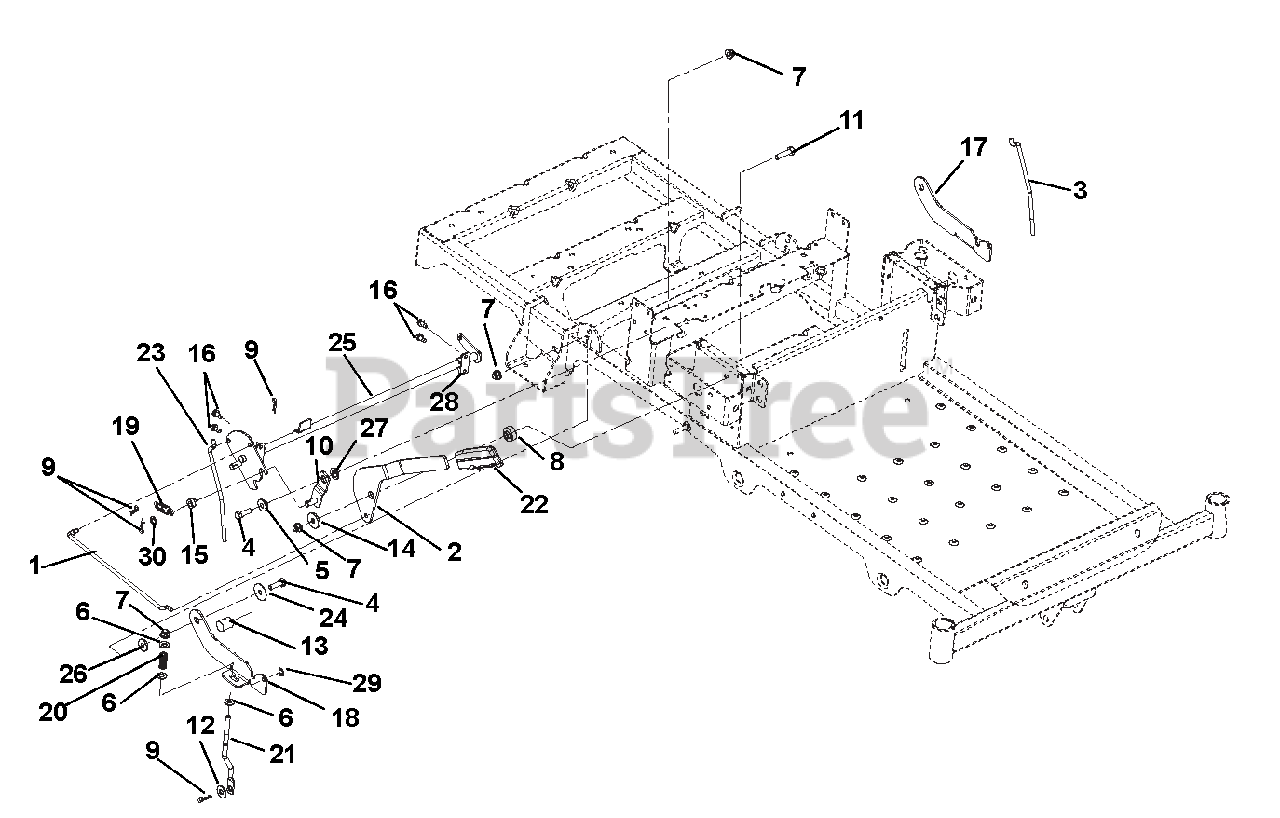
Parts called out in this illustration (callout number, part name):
1	LINK, BRAKE HANDLE
2	HANDLE, PARKING BRAKE
3	LINK, NEUTRAL LH
4	@BLT-HEX .31-18X1.00 GR5 YWZC
5	BSHG-FLG .32X.500X.344X.880
6	@WSHR-FL-STL.344X.688X.065YWZC
7	@NUT-LK-NYL-FLG .31-18 YWZC
8	SPCR,BRAKE .32X.49X.192X1.00
9	PIN-HAIR INT .08X.18X1.18 YWZC
10	WELDMENT,DETENT ARM
11	@BLT-HEX .31-18X1.25 GR5 YWZC
12	@WSHR-FL-STL.38X.875X.083 YWZC
13	TRUNION, 1/4-20
14	WSHR-FL-STL .344X1.125X.135
16	SCR-TAP .25-20X.50 HWH TR YWZ
17	LATCH, LH NEUTRAL
18	LATCH, RH NEUTRAL
19	SG-TENS .072X.565X1.87
20	SPRING, COMPRESSION
21	LINK, BRAKE COG
22	GRIP, PARKING BRAKE (YELLOW)
23	LINK, NEUTRAL RH
24	WSHR-FL-STL .347X1.254X.048YWZ
25	WLDMT, BRAKE SHAFT
26	BSHG, FLG .325X.499X.26X.88
27	WSHR-FL-STL .52X.827X.062 YWZC
28	BUSHING-.50 CLAMP BLOCK MOLDED
29	RG-RTNG-EXT .250X.025
30	WSHR,.385X.745X.030 STL YWZC
